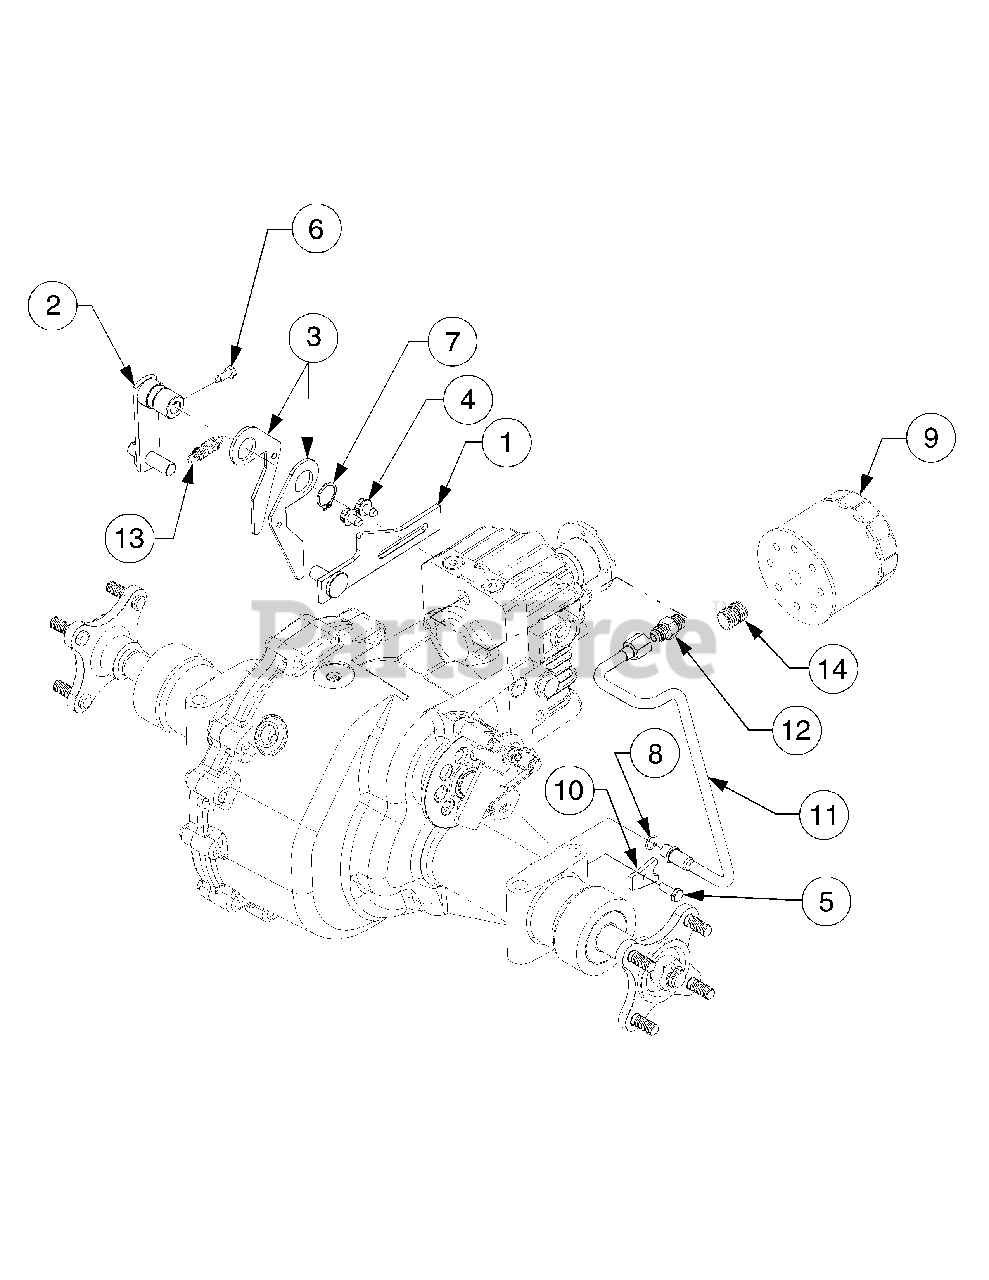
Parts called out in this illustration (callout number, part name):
1	Bracket, Neutral Return
2	Arm Assembly, Control
3	Arm, Neutral
4	Screw, Hex Wash Hd Tapp, 5/16-18 x .50
5	Screw, Hex Cap, 1/4-20 x .75 GR5
6	Screw, Special Hex Cap, 5/16-24 x .625
7	Ring, Snap, .875 Shaft
8	O-Ring, .426 ID x .566 OD x .07
9	Filter, Oil
10	Clamp, Tube, .50
11	Tube, Hydro Pickup
12	Fitting, Hydraulic
13	Spring, Extension
14	Nipple, Oil Filter
